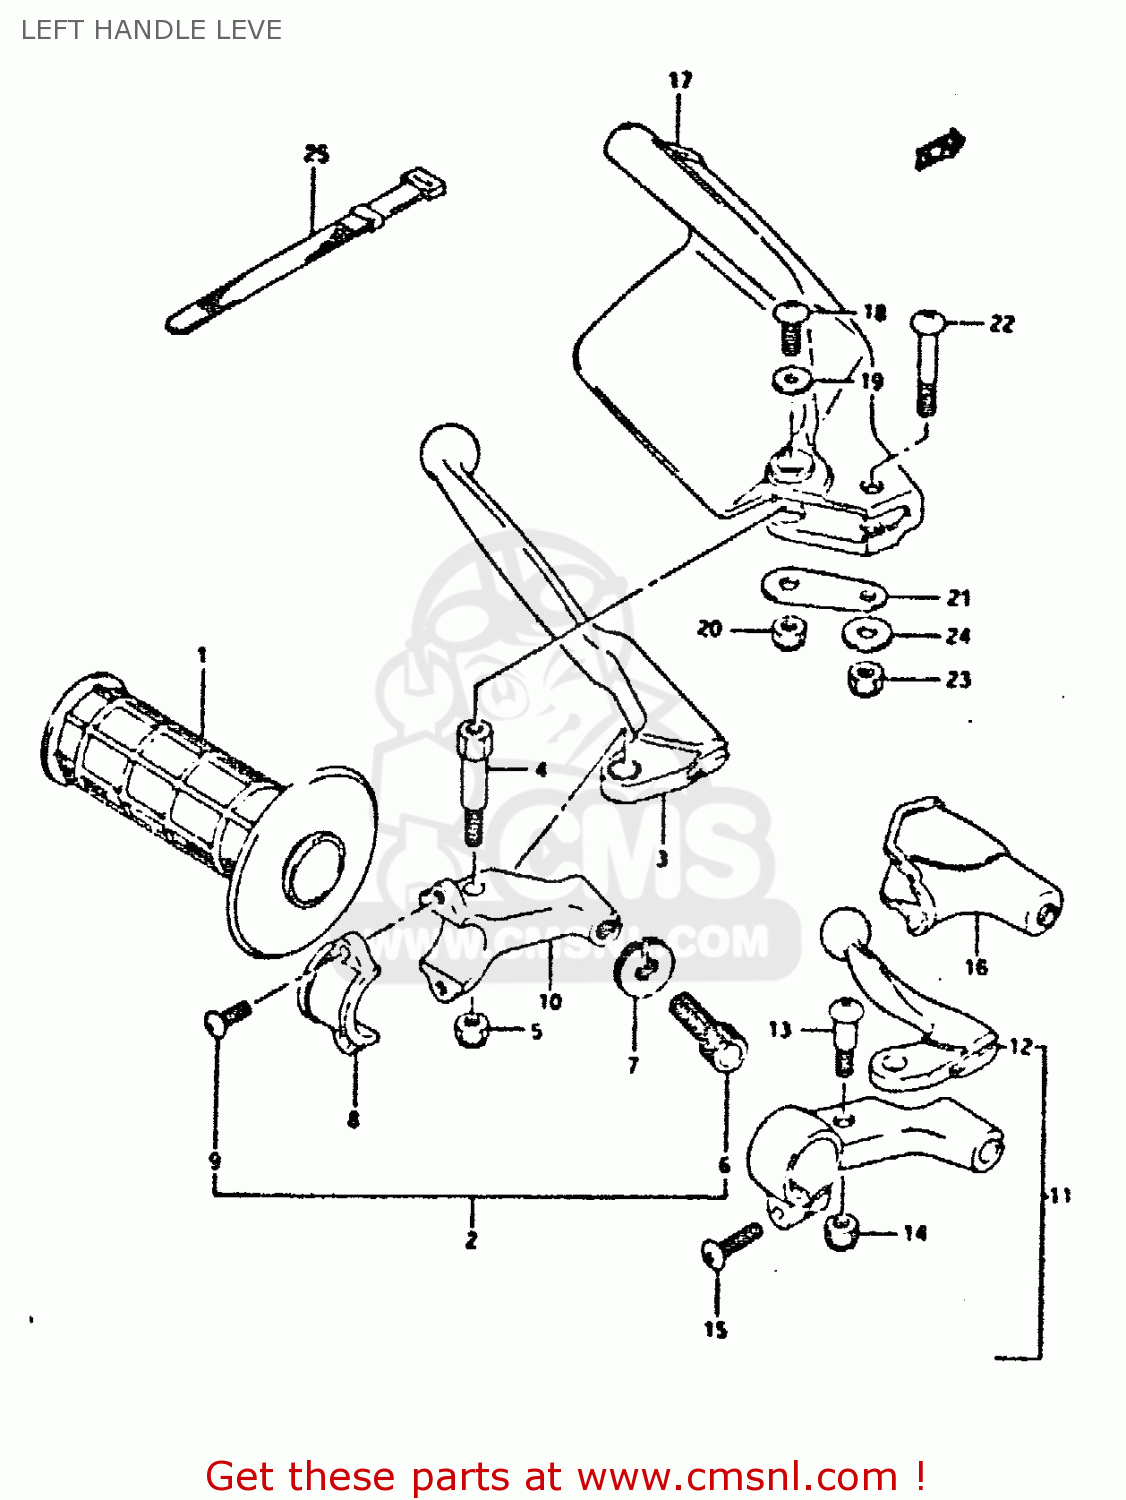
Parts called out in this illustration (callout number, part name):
1	GRIP,L
2	LEVER ASSY,CLUTCH
3	LEVER,CLUTCH
4	BOLT,LEVER SET
5	NUT 6MM
6	ADJUSTER,CABLE
7	NUT,LOCK
8	BRACKET,CLUTCH LEVER HOLDER
9	SCREW
10	HOLDER,CLUTCH LEVER
11	LEVER ASSY, DECOMP
12	LEVER,DECOMP
13	BOLT,LEVER PIVOT
14	NUT
15	SCREW
16	COVER,DECOMP LEVER DUST
17	COVER,KNUCKLE,L
18	SCREW
19	WASHER (5.5X16X1.2)
20	NUT 6MM
21	PLATE, COVER, LOWER
22	SCREW
23	NUT 6MM
24	WASHER (6.5X17X1.6)
25	CLAMP(L:120)
